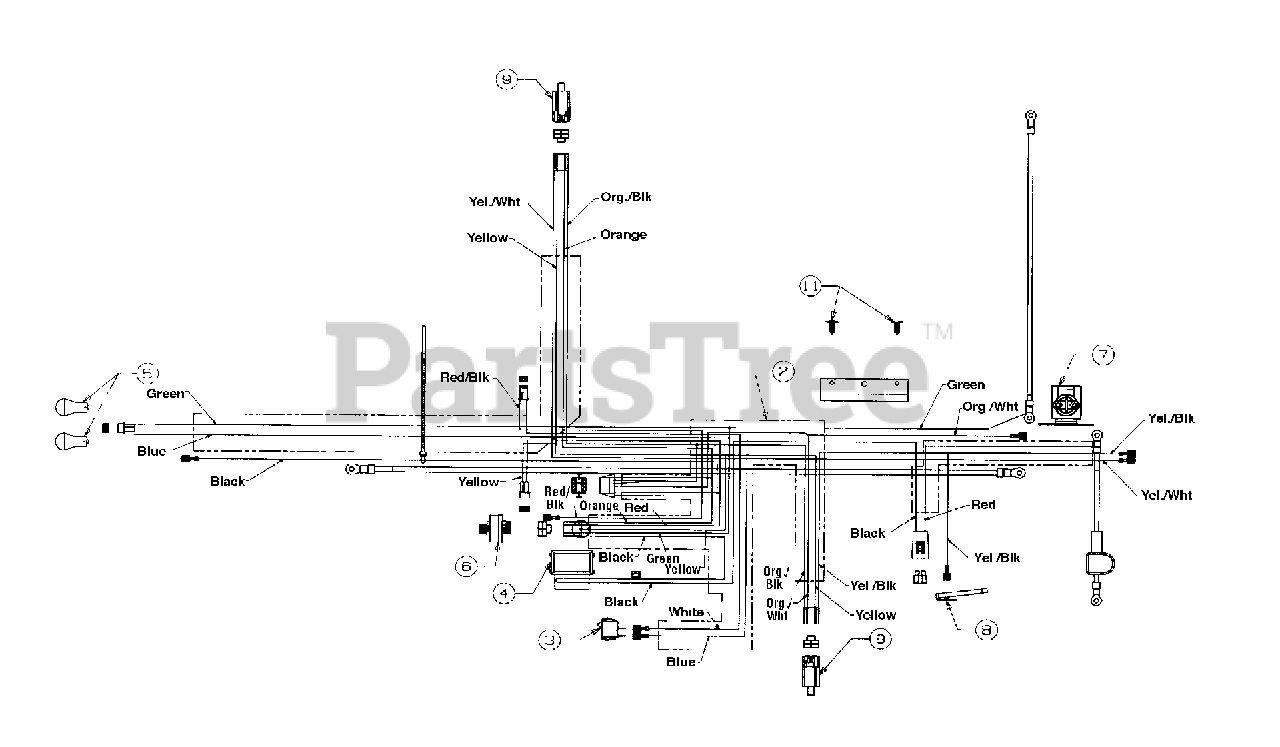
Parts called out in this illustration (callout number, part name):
2	Wire Harness w/Light Switch and Amp
3	Light Switch
4	Ammeter
5	Bulb
6	Ignition Switch
7	Solenoid
8	Safety Switch
9	Safety Switch
11	Ratchet
